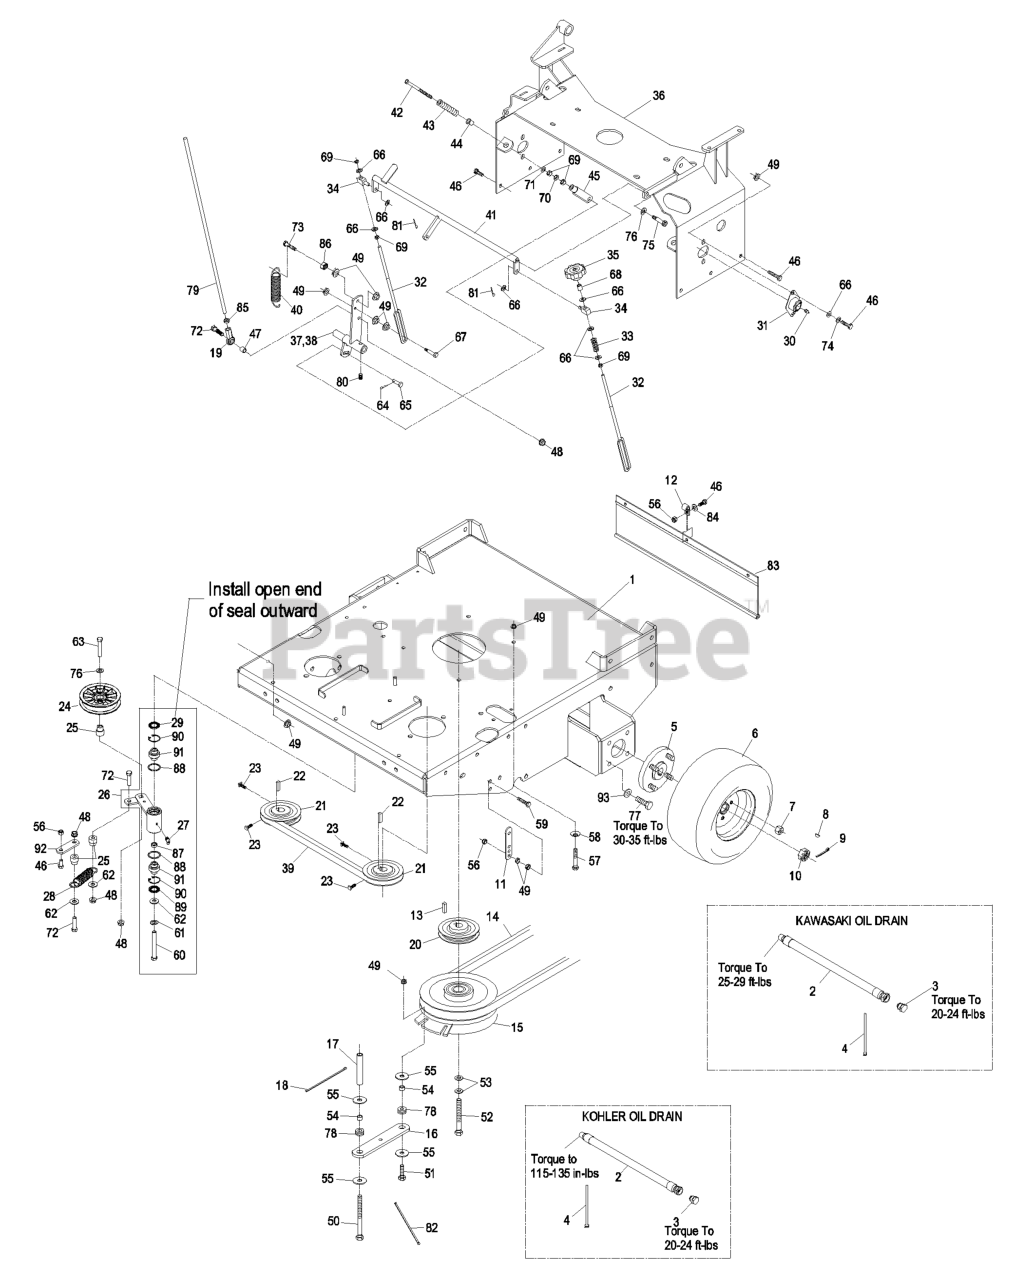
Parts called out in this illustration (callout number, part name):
4	TIE-PLASTIC
6	ASM, DRIVE TIRE
7	NUT-LUG
8	KEY-WOODRUFF
9	PIN-COTTER
10	NUT-HEX, SLOTTED
11	TAB-SPRING, EXTENSION
12	CLIP-LOOM
14	BELT,B 83.65
15	CLUTCH ASM
16	STRAP-CLUTCH, BRAKE
17	SPACER,SHIELD
18	TIE-CABLE
19	JOINT-BALL END, LH
20	PULLEY
21	SHEAVE ASM
23	SCREW-SET
24	PULLEY-IDLER, FLAT
25	BUSHING-IDLER
26	KIT,IDLER ARM W/BRGS.
27	FITTING-GREASE, 90 DEG
28	SPRING-EXTENSION
29	SEAL-LIP, SINGLE
30	FITTING-GREASE
31	BEARING-FLANGE, SIDE
32	LINK,SPEED CONTROL
33	SPRING-COMPRESSION
35	KNOB-TRACKING
37	WLD,LH CONTROL ARM
39	BELT,COG A-59.5
40	SPRING-EXTENSION
41	WLD,CRANK SPEED CNTRL
42	BOLT-RETURN, NEUTRAL
43	SPRING,COMPRESSION (NEUT)
44	BUSHING-FLANGED
45	YOKE-ADJUSTABLE
46	SCREW-HH
47	TUBE,PUMP LINK SPACER
48	NUT-HHF, WHIZ
50	SCREW-HH
51	SCREW-HH
52	SCREW-HH
53	WASHER-SPRING
56	NUT-LOCK, NI
57	SCREW-HH
58	WASHER-SPRING
59	BOLT-TAP, HH
60	SCREW-HH
61	WASHER-LOCK
62	WASHER-FLAT
63	SCREW-HH
64	PIN-COTTER
65	PIN-CLEVIS
66	WASHER-PLAIN
67	SCREW-HH
69	NUT-HEX
70	NUT-JAM
71	WASHER-FLAT
72	SCREW-HH
73	SCREW-HH
74	WASHER-LOCK
75	SCREW-HSH
76	WASHER-FLAT
77	SCREW-HH
78	GROMMET
79	LINK,DRIVE (PLTD)
80	SCREW-SET
81	PIN-COTTER
82	TIE-PLASTIC
83	SHIELD,DRAG
84	WASHER-FLAT
85	NUT-HEX JAM, LH
86	NUT-JAM
89	SEAL-LIP, DOUBLE
90	RING-SNAP
91	BEARING-SPHERICAL
92	ARM-LIFT, DECK
93	WASHER-BELLEVILLE
